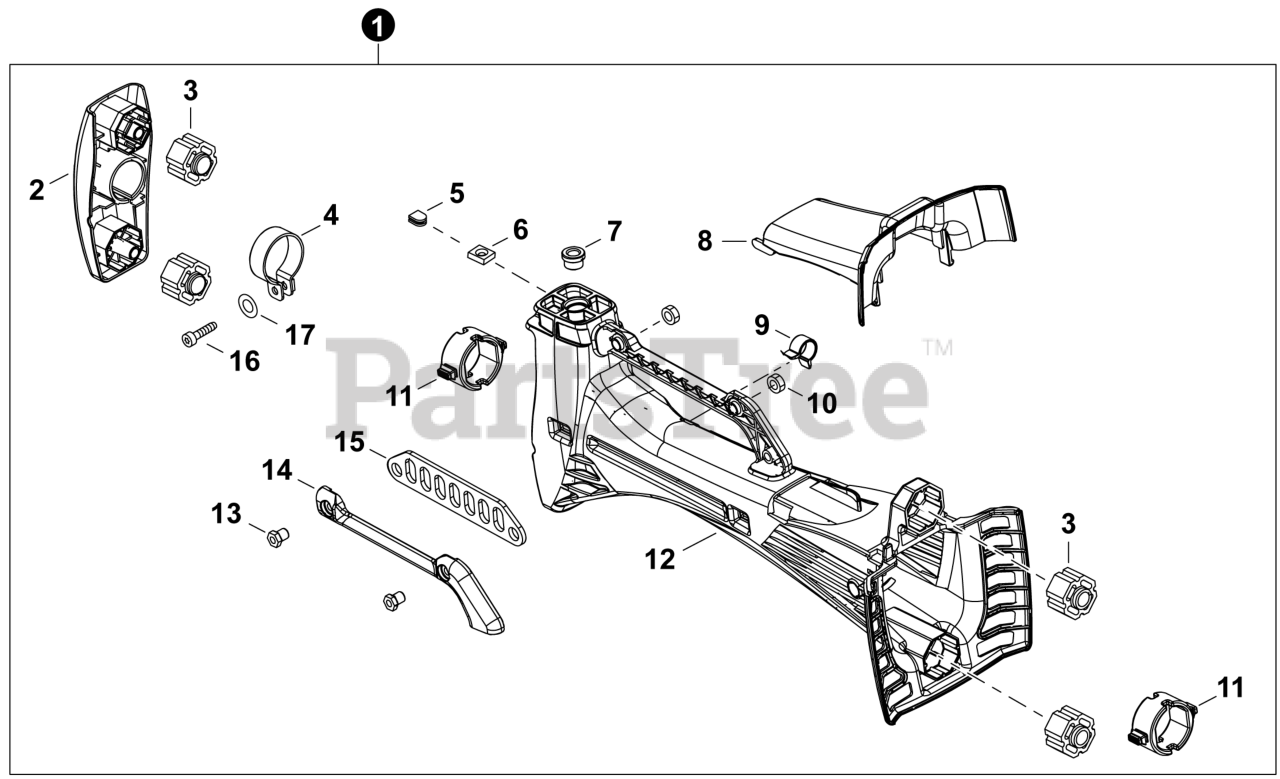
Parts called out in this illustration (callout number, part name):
1	HANDLE ASSY - SUPPORT
2	BRACKET, CUSHION
3	CUSHION
5	GROMMET, PLUG
6	NUT 8×1.25
7	COLLAR 8
8	GUIDE, CABLE
11	STOPPER, HANDLE
12	SUPPORTER, HANDLE
13	BOLT, TORX 5×16
15	PLATE, EYE
16	BOLT, TORX 6×20
17	WASHER 6.5×13×1
